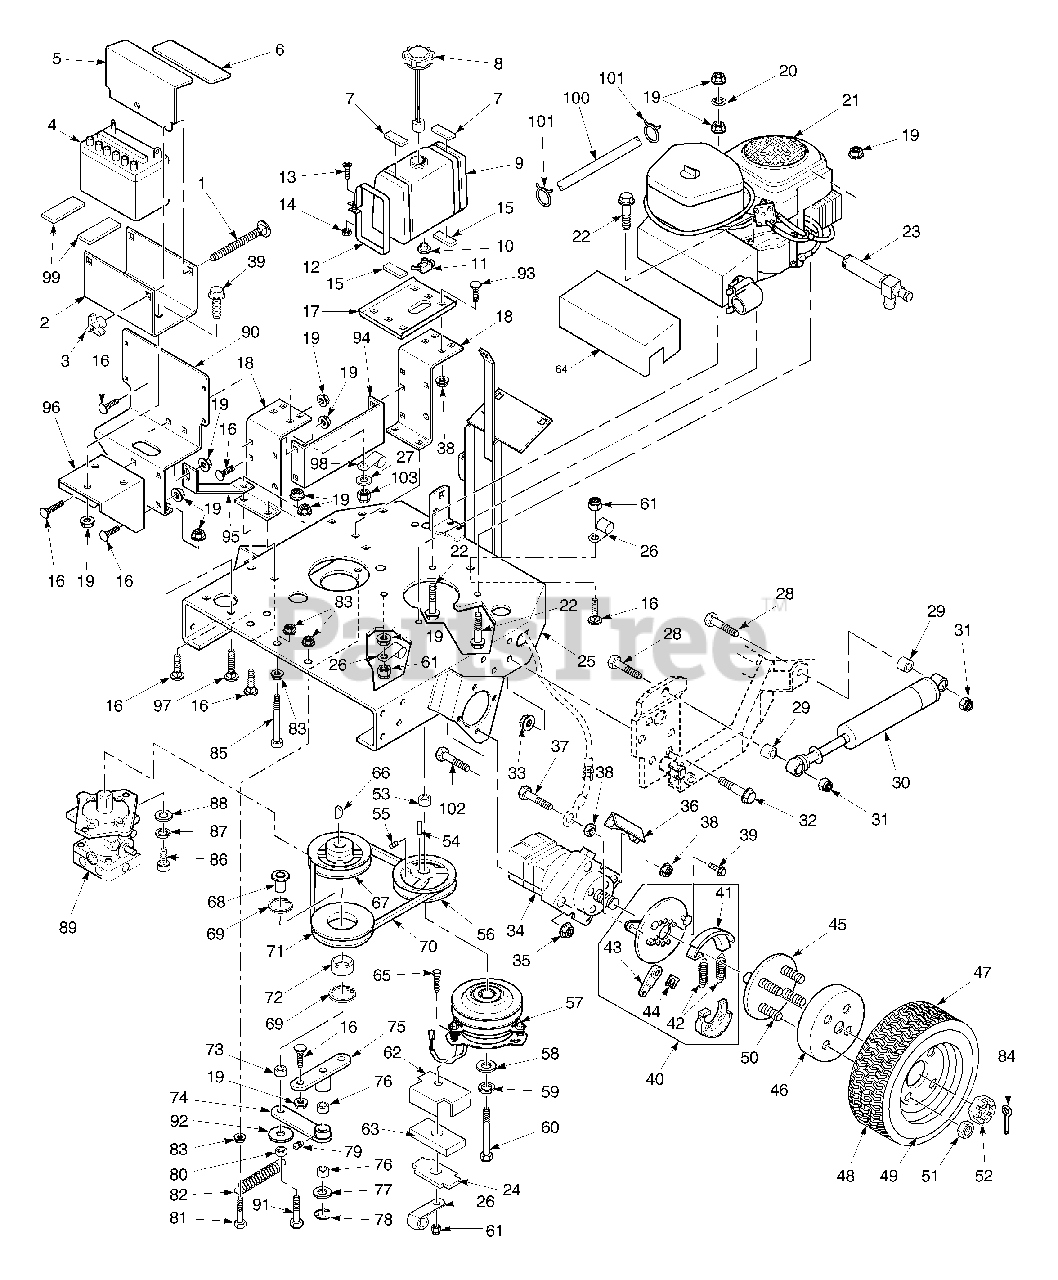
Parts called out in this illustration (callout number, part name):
1	Carriage Bolt, 1/4-20 x 6"
2	Battery Box
3	Nut, Wing 1/4-20
4	Battery
5	Battery Cover
6	Insulation, Battery Cover
7	Pad, Fuel Tank Strap
8	Cap, Fuel Tank
9	Fuel Tank Assy.
10	Bushing, Fuel Tank Valve
11	Fuel Shut Off Valve
12	Strap, Fuel Tank
13	Phil RDHD Machine Screw 1/4-20 x 2"
14	Hex Nut, 1/4-20
15	Pad, Fuel Tank Support
16	Carriage Bolt, 5/16-18 x 3/4"
17	Support, Fuel Tank
18	Bracket, Fuel Tank Support
19	Serr. Fl. Hex Nut 5/16-18
20	Lockwasher, 5/16 Int. Tooth
21	Engine, 23 HP Kohler CV, (Spec PS-75523)
22	Hex Head CPSCR, 5/16-18 x 1-3/4"
23	Oil Drain Extension
24	Plate, Backing
25	Engine Deck
26	Wire Loom, .50 I.D.
27	Washer, 1/4 (.312 x .750 x .065)
28	Bolt, Hex Head 1/2-13 x 2"
29	Sleeve, Shock Absorber Mount
30	Shock Absorber
31	Hex Locknut, Elastic Stop 1/2-13
32	Serr. Fl. Hex Head CPSCR, 7/16-14 x 1"
33	Serr. Fl. Hex Nut, 7/16-14
34	Motor - White
35	Lockwasher, 1/2"
35A	Nut, 1/2-13
36	Anchor, Brake
37	Bolt, Hex Head 1/4-20 x 1-1/4"
38	Serr. Fl. Hex Nut, 1/4-20
39	Serr. Fl. Hex Head CPSCR, 5/16-18 x .75"
40	Parking Brake Assembly
41	Brake Pads- Pair
42	Springs - Pair
43	Actuating Arm,
45	Hub Assembly
46	Brake Drum
47	Rim and Tire Assembly
48	Tire 20 x 10 x 10, 4 Ply
49	Rim Only
50	Bolt, Hub
51	Wheel Nut
52	Castle Nut, 1.0-20 UNEF
53	Spacer, Clutch
54	Key, 1/4 x 1/4 x 2"
55	Hex Socket Set Screw, 5/16-18 x 3/8"
56	Pulley, Engine Pump Drive
57	Clutch, Electric (Ogura)
58	Flatwasher, 7/16 (.469 x 1.75 x .25)
59	Lockwasher, 7/16"
60	Bolt, Hex Head 7/16-20 x 2.75"
61	Hex Locknut, Elastic Stop 5/16-18
62	Backing Plate, Clutch Stop
63	Rubber Pad, Clutch Stop
64	Heatshield, Muffler
65	Bolt, Hex Head 5/16-18 x 1-3/4"
66	Key, Woodruff 3/16 x 5/8"
67	Pulley, Pump Input
68	Sleeve, Idler
69	Ring, Retaining, 1-9/16 Internal
70	Belt, Pump Drive
71	Pulley, Idler-Traction Drive
72	Bearing, Idler Pulley
73	Spacer, Idler
74	Pump Idler Arm
75	Idler Pivot Base
76	Bushing, Oillube
77	Flatwasher, 3/4"
78	Ring, Retaining, 3/4" Ext. "E"
79	Grease Fitting
80	Hex Nut, Jam 3/8-16
81	Bolt, Hex Head 3/8-16 x 3-1/4"
82	Spring, Pump Drive Idler
83	Serr. Fl. Hex Nut, 3/8-16
84	Cotter Pin, 5/32 x 1.50"
85	Bolt, Hex Head 3/8-16 x 5"
86	Socket Head CPSCR, 1/2-13 x 1-1/4"
87	Lockwasher, 1/2"
88	Flatwasher, 1/2 (.516 x .938 x .105)
89	Pump, Sundstrand
90	Bracket, Oil Tank Support
91	Bolt, Hex Head 3/8-16 x 1-3/4"
92	Washer 2" OD, 3/8 ID, 16 Ga.
93	Carriage Bolt, 1/4-20 x 3/4"
94	Guard, Pulley
95	Gusset, Battery Box
96	Support, Battery Box
97	Carrage Bolt, 5/16-18 x 1"
98	Wire Loom, .75" I.D.
99	Rubber Pad
100	Fuel Hose, Order by the inch
101	Clamp, Fuel Hose
102	Bolt, 1/2-13 x 2.50"
103	Nut, 1/4-20 Elastic Stop
